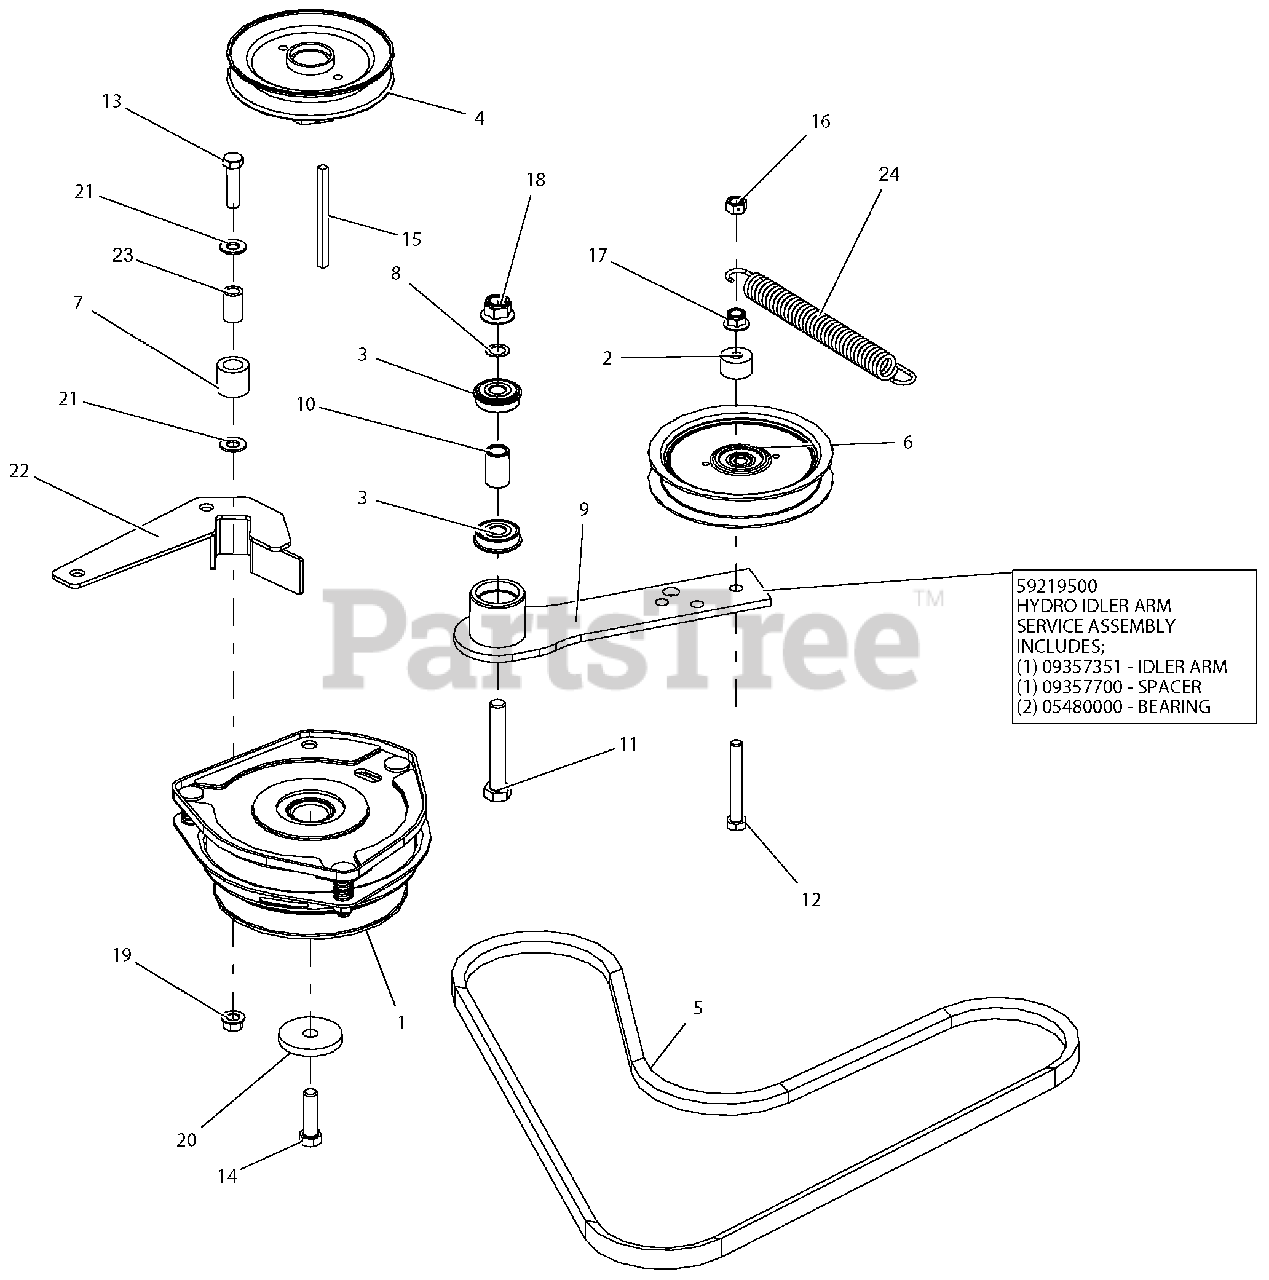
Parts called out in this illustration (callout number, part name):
1	CLUTCH-OGURA
2	SPACER .390X1.000X.562
3	BRG, BALL .501 X 1.38 X .438 SEALED
4	PULLEY, V-5.25 OD X 1.51 ID
5	BELT, B RAW COGGED
6	IDLER, FLAT - 5.00" X .75"
7	BUMPER, RUBBER .62 X 1.0 X .88 LG
8	WASHER-FLAT-STL, .500 X .750 X .020
9	WLDMT, HYDRO DRIVE IDLER ARM-BLACK
9	HYDRO IDLER ARM SERVICE ASSEMBLY INCLUDES -
9	IDLER ARM
10	SPACER, .510 X .750 X 1.148
11	BLT-HEX .50-13X3.00 GR5 YWZC
12	BLT-HEX .38-16X2.75 GR5 YWZC
13	BLT-HEX .38-16X1.50 GR5 YWZC
14	BLT-HEX .44-20X1.50 GR8 YWZC
15	KEY-SQ .250X.250X3.50
16	NUT-LK-CTR .38-16 YWZC
17	NUT-LK-NYL-FLG .38-16 YWZC
18	NUT-LK-NYL-FLG .50-13 YWZC
19	NUT, LK-TOP-FLG .38-16 YWZC
20	WSHR-FL-STL .469X2.00X.25 YWZC
21	WSHR-FL-STL.406X.812X.065 YWZ
22	WMT, CLUTCH STOP - BLACK
23	BUSH.,S.391X.622X.95 ST REV A
24	SPRG, EXTENSION .120X.845X6.55 WLD
